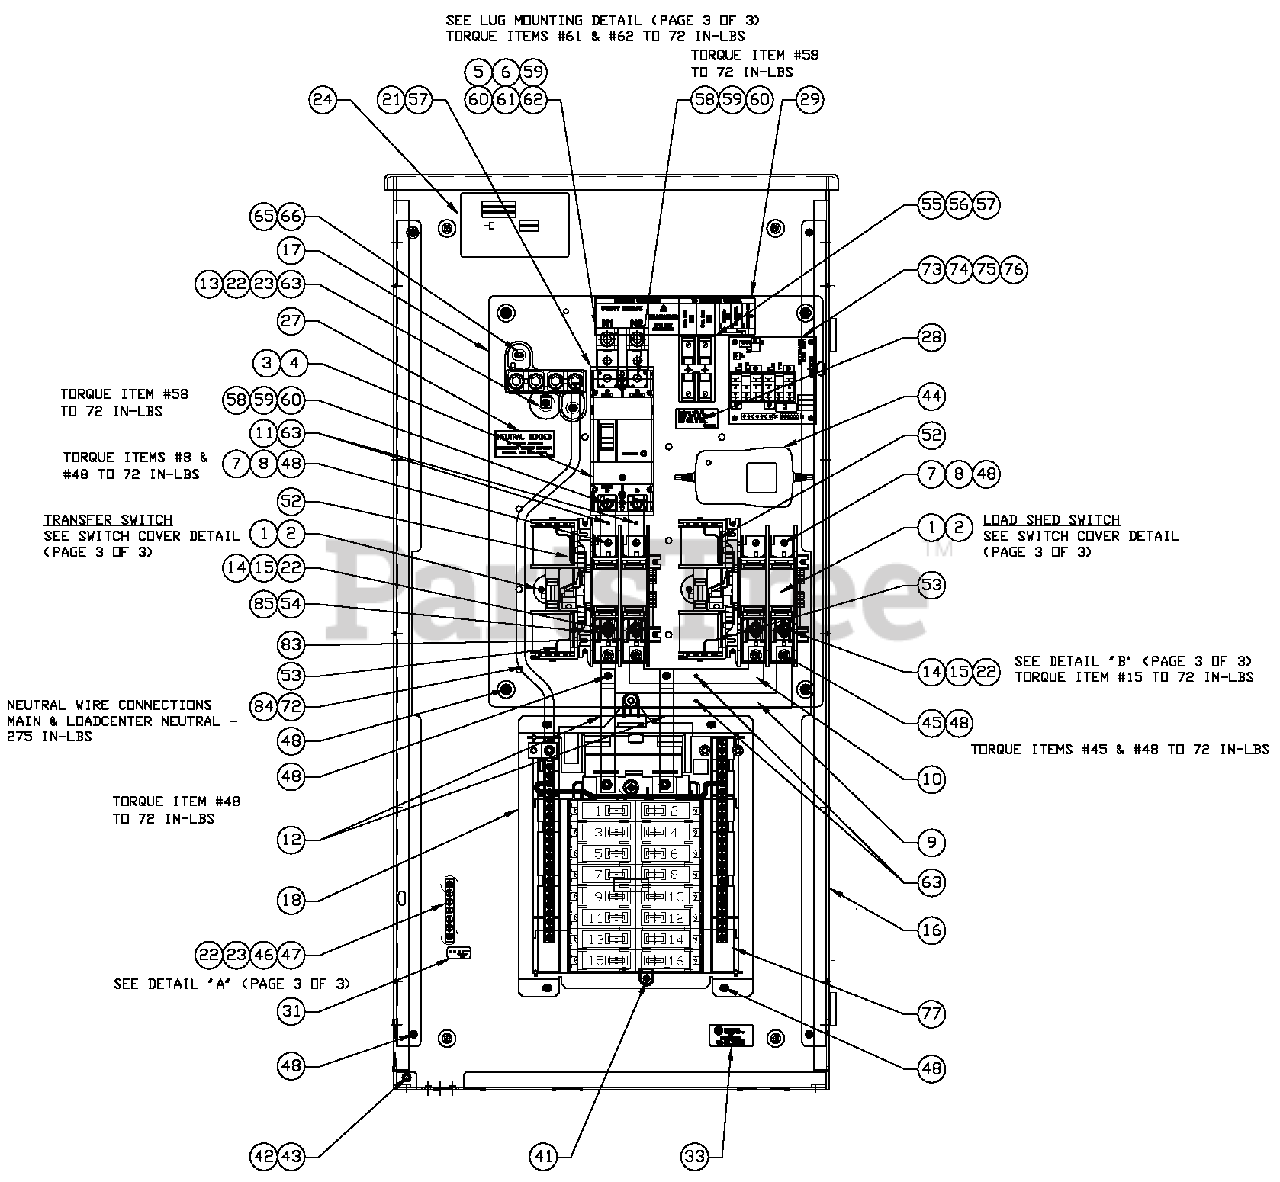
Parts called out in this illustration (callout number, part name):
1	TRANSFER SW. HSB 200A 2P 250V
2	SCREW HHTT M5-0.8X 10 BP
3	CIRCUIT BREAKER, 200A 2-POLE
4	SCREW RHM #8-32X3-1/4
5	BUSBAR, 200A LUG ADAPTER
6	LUG 300 MCM-6STR
7	SPACER 200 AMP TRANSFER
8	BOLT CARR 1/4-20X1"
9	BUSBAR, 200A TRANSFER SW T1
10	BUSBAR, 200A TRANSFER SW T2
11	BUSBAR, 200A TRANSFER SW N1,N2
12	BUSBAR, PANELBOARD INTERCONNECTION
13	BUSBAR, NE UTRAL BLOCK
14	LUG SOLDERLESS 250-#6 AL/C U
15	SCREW BHSC 1/4-20X3/8
16	ENCLOS URE,LOAD SHED TRANSFER SWITCH
17	SUBPLATE PANELBOARD
18	SUBPLATE, LOADCENTER
19	INSIDE COVER LOAD SHED
20	COVER LOAD SHED ENCLOS URE
21	CB BRKT 200A TRANSFER SWITCH
22	WASHER LOCK M6-1/4
23	NUT HEX 1/4-20 SS
24	DECAL, TRANSFER SWITCH DATA
25	DECAL, TRANSFER SWITCH DATA 200
26	DECAL, WARN MANUAL OPER HANDLE
27	DECAL, FRT GTS LDC TR16 CIR GRY
28	DECAL, NEUTRAL CONNECTION
29	DECAL, FUSE REPLACEMENT
30	DECAL, CUSTOMER CONNECTION
31	DECAL, TEST SEQUENCE
32	DECAL, GROUNDING LUG
33	DECAL, TERMINAL SHOCK HZD BI
34	DECAL, ULPANELBOARD
35	DECAL, LIVE CIRCUIT ENG/FRN/SPN
36	DECAL, TRANSFER SWITCH INFO
37	DECAL, UTILITY SERVICE DISCONNECT
38	DECAL, GENERATOR SOURCE CONNECTION
39	DECAL, NON-ESSENTIAL LOAD CONN
40	DECAL TRANSFER SWITCH RTS
41	SCREW HHTT M5-0.8X 16
42	NUTTRIC 1/4-20 X .525
43	THUMB SCREW 1/4-20x1/2
44	BATTERY CHARGER ASSEMBLY
45	SCREW BHSC 1/4-20X3/4
46	GRO UND BAR (5) 2-14 AWG CONN
47	WASHER SHAKEPROOF EXT 1/4 STL
48	NUT HEX FL WHIZ 1/4-20
49	BRACKET, ARM EXTENDER
50	RIVET POP .156 X .362 AL
51	ARM EXTENDER PIN
54	WIRE-E1
55	FUSE BLOCK 30A 600V 2 POLE
56	FUSE 5A X BUSS HLDR73591
57	SCREW HHTT M4-0.7X 10 BP
58	SCREW SHCM8-1.25X 20 G8
59	WASHER FLAT 5/16-M8 ZINC
60	WASHER LOCK M8-5/16
61	NUT HEX M8-1.25 G8 CLEAR ZINC
62	SCREW HHCM8-1.25X 25 C8.8
63	SCREW HHTT #8-32X1/4 CZ
65	ASSY-NEUT BLK 200-400A W/TAP
66	SCREW HHTT M6-1.0X 12 MM
67	KEYPAD, LOAD SHED
68	ASSY PCB INTFC LOAD SHED KEYPD
69	NUT HEX LOCK M4-0.7 SS NYL INS
70	SPACER M4/#8 X 5/16 X 1/4 NYL
71	CABLE, KEYPAD INTERFACE
72	NEUTRAL WIRE
73	ASSY PCB 2008HSB LOAD SHEDCTRL
74	RELAY SOC 12VDC DPDT 10A@240VA
75	SPACER.20X.375X.375 PL
76	NUT HEX FL WHIZ M5-0.8
77	16 CIR L/CENTR 200A/240V SIEMS
78	CB0 020A 2P PLUGIN
79	CB0 015A 1P PLUGIN
80	CB0 020A 1P PLUGIN
81	CB0 040A 2P PLUGIN
82	CB0 050A 2P PLUGIN
83	STRAIGHT SPADE CONNECTOR
84	TIE-WRAP MOUNT(FIR TREE SYTLE)
